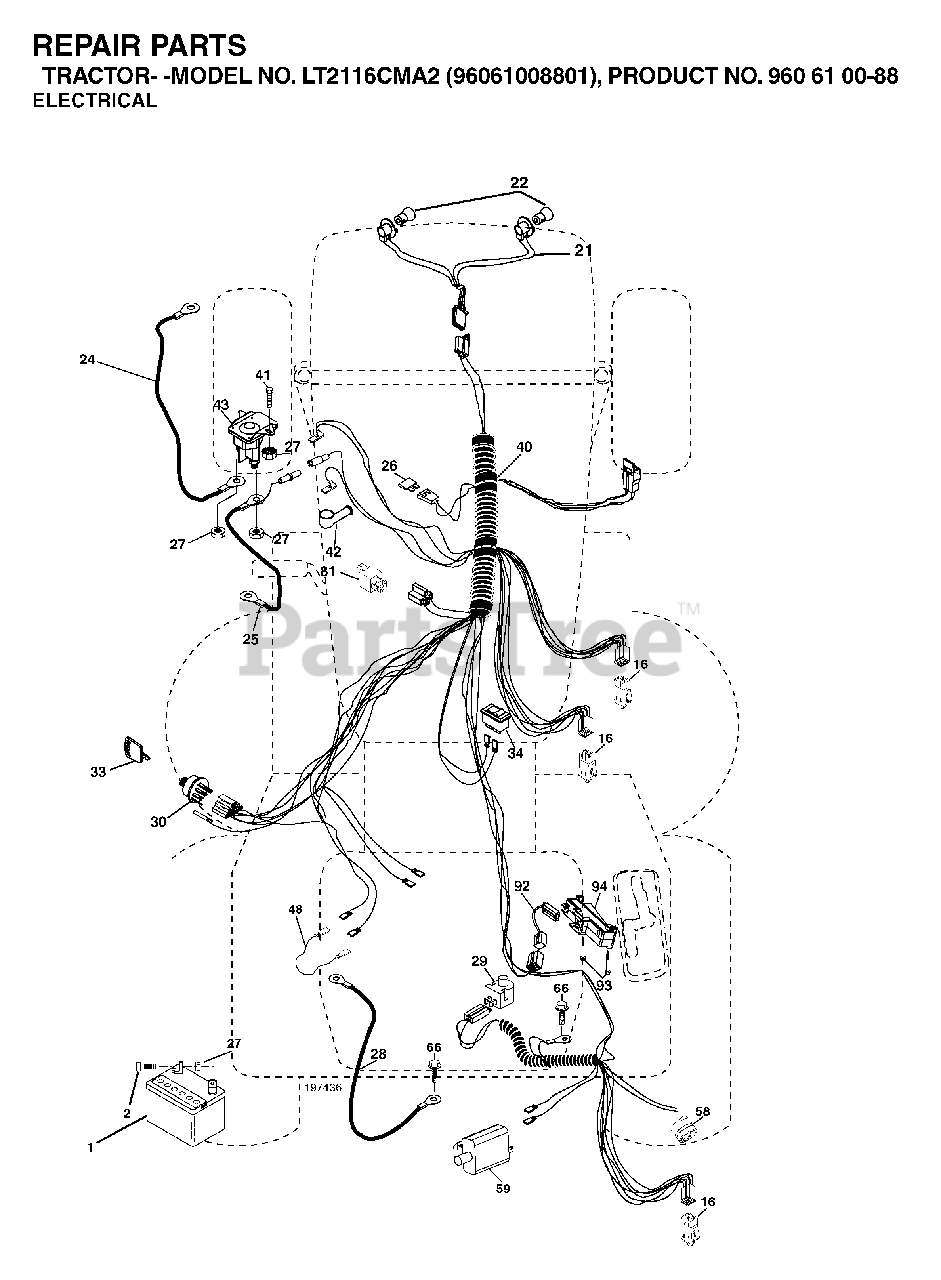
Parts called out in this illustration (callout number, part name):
1	BATTERY 12V .35 AMP
16	SWITCH INTERLOOK PUSH-IN
21	HARNESS ASSY LIGHT
22	LIGHTBULB
24	CABLE ASM
25	CABLE BATTERY
26	FUSE 20AMP
27	NUT
28	CABLE GROUND
29	SWITCH.SEAT.DP W/RAMPS
30	SWITCH.IGN.DELTA.W.LGH.ROS
33	KEY MLD GEN DELTA
34	SWITCH LT
42	TERMINAL COVER
43	SOLENOID.W/BRASS.PLUNG
58	BUZZER
81	RELAY.ASSY.T
92	HARNESS.PIGTAIL.CONSLE
93	SCREW.PLASTITE
94	MODULE.REVERSE.ROS
